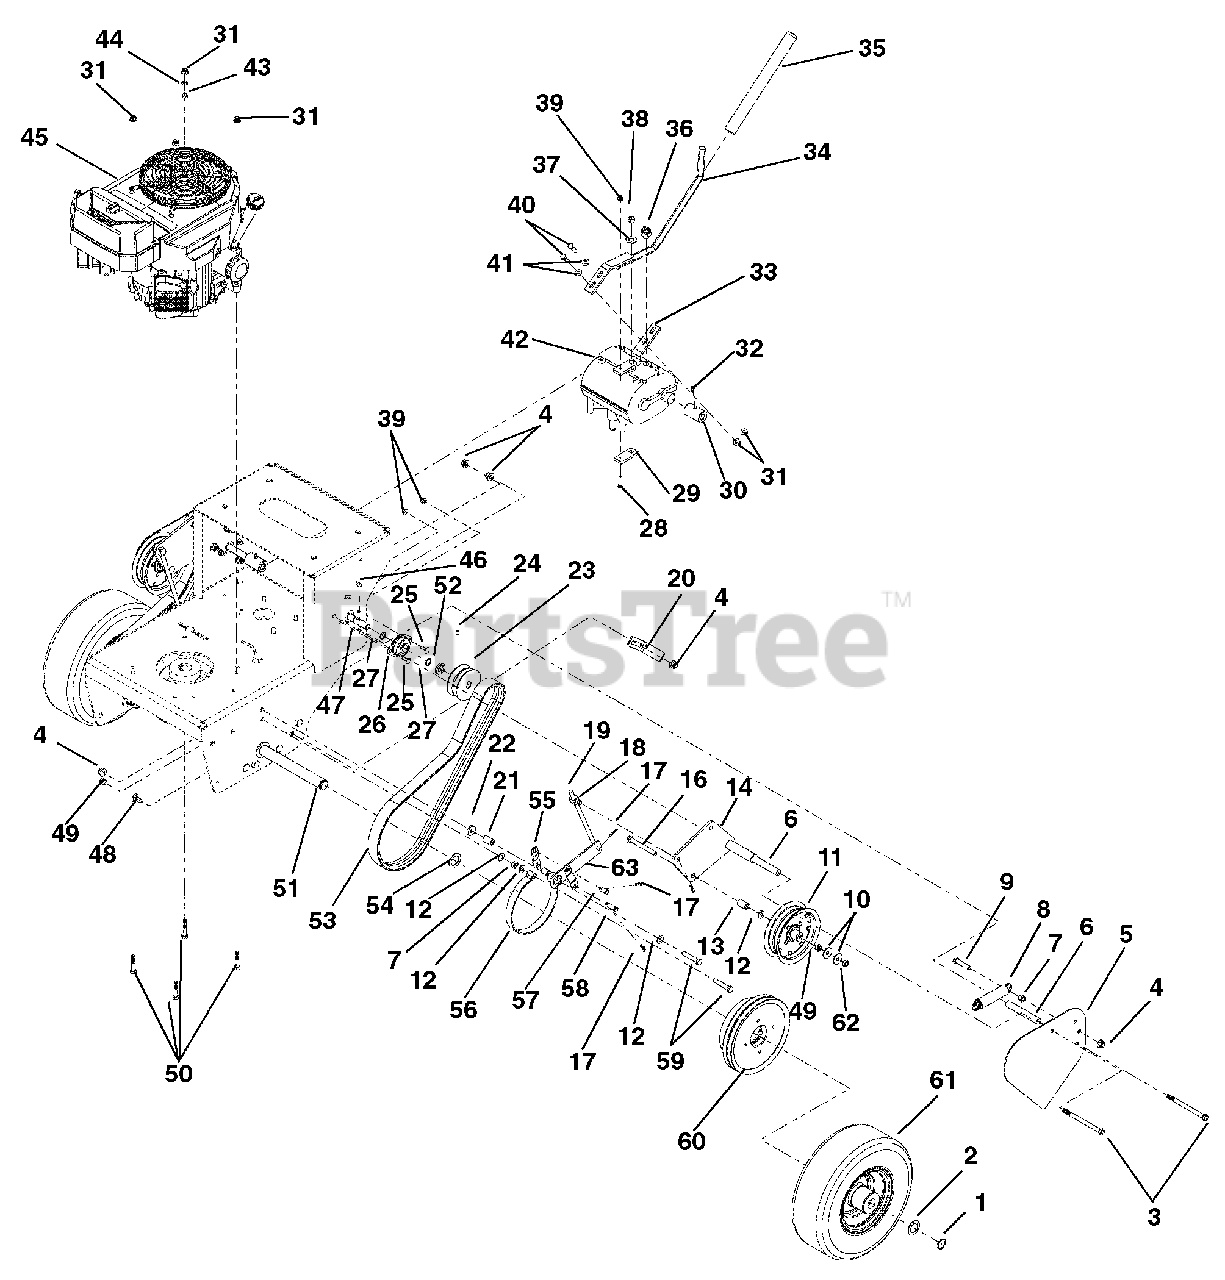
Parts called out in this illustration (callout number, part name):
1	Ring-Retaining-External 1.00 x .078
2	Washer, Flat-Steel 1.010 x 1.505 x .062
3	Bolt, .38-16 x 5.00 Hex Grade 5
4	Nut, Nyloc Flange, .38-16
5	Cover, Traction Belt
6	Bushing, S.385 x .610 x 4.32 Steel
7	Nut, .375-16 Standard Hex Grade 5
8	Spring-Tension .105 x 1.00 x 5.0
9	Bolt, .38-16 x 1.75 Hex Grade 5
10	Washer, Flat Steel .375 x 1.125 x .065
11	Assembley, Idler 4"
12	Washer, .406 x .813 x .065 Flat
13	Bushing, Sleeve .375 x .625 x 1.000
14	Weldment, Wheel Clutching Arm-Left Hand
15	Weldment, Wheel Clutching Arm-Right Hand
16	Bolt, Round Head Square Neck .38-16 x 3.5 Grade 5
17	Pin, Hair
18	Swivel, .375-24
19	Rod, Brake Actuating
20	Plate, Belt Finger
21	Bushing, S.391 x .622 x .95 St
22	Washer, Flat Steel .406 x 1.00 x .188
23	Sheave, Drive 3.25 OD x .625 ID
24	Screw, Set .31-18X.38 Socket Head
25	Bolt, .25-20 x .750 Round Head Square Neck Grade 5
26	Bearing, Flange .625 x 1.875 x .797
27	Ring, Retaining-External .579 x .035
28	Bolt, .25-20 x 1.00 Hex Grade 5
29	Plate, Shift
31	Nut, Nyloc Flange, .31-18
32	Fitting, .25-28 STRGT Grease Zerk
33	Bracket, Shift Lever
34	Weldment, Shift Lever
35	Grip, Handlebar
36	Switch, Neutral Start (N.O.)
37	Washer, Locking .375 x .130
38	Nut, Locking-Center .375-24
39	Nut, Nyloc Flange, .25-20
40	Bolt, .3125-18 x 1.00 Hex Grade 5
41	Washer, Flat Steel .344 x .688 x .065
42	Transmission
43	Nut, Locking-Center Jam .31-18
44	Washer, Locking-EXT .326 x .599 x .031
45	Engine, KAWI FH381V KAI (143, 144)
46	Key, Woodruff .19 x .75 HRD#9
47	Shaft, Half
48	Bolt .38-16 x .750 Round Head Square Neck Grade 5 LN
49	Locknut, .375-16 Center
50	Bolt, .3125-18 x 1.75 Hex Grade 5
51	Shaft, Axle
52	Washer, Flat .765 x 1.125 x .187
53	Belt, Gear Drive 49" Elbow COG
54	Washer, Hard-Thrust 1.007 x 1.542 x .062
55	Link, Brake Arm
56	Assembly, Brake Band, Pro
57	Pin, CVS .375 x .750 x .516
58	Pin, Clevis .38 x 1.25
59	Bolt, .375-16 x 2.00 Hex Grade 5
60	Assembly, Pulley and Drum
61	Assembly, Wheel and Tire 6 x 3.5 (143)
62	Nut, Locking-Jam-Center .375-16
63	Weldment, Brake Actuating Lever
NA	Air Filter
NA	Oil Filter
NA	Fuel Filter
NA	Spark Plug
